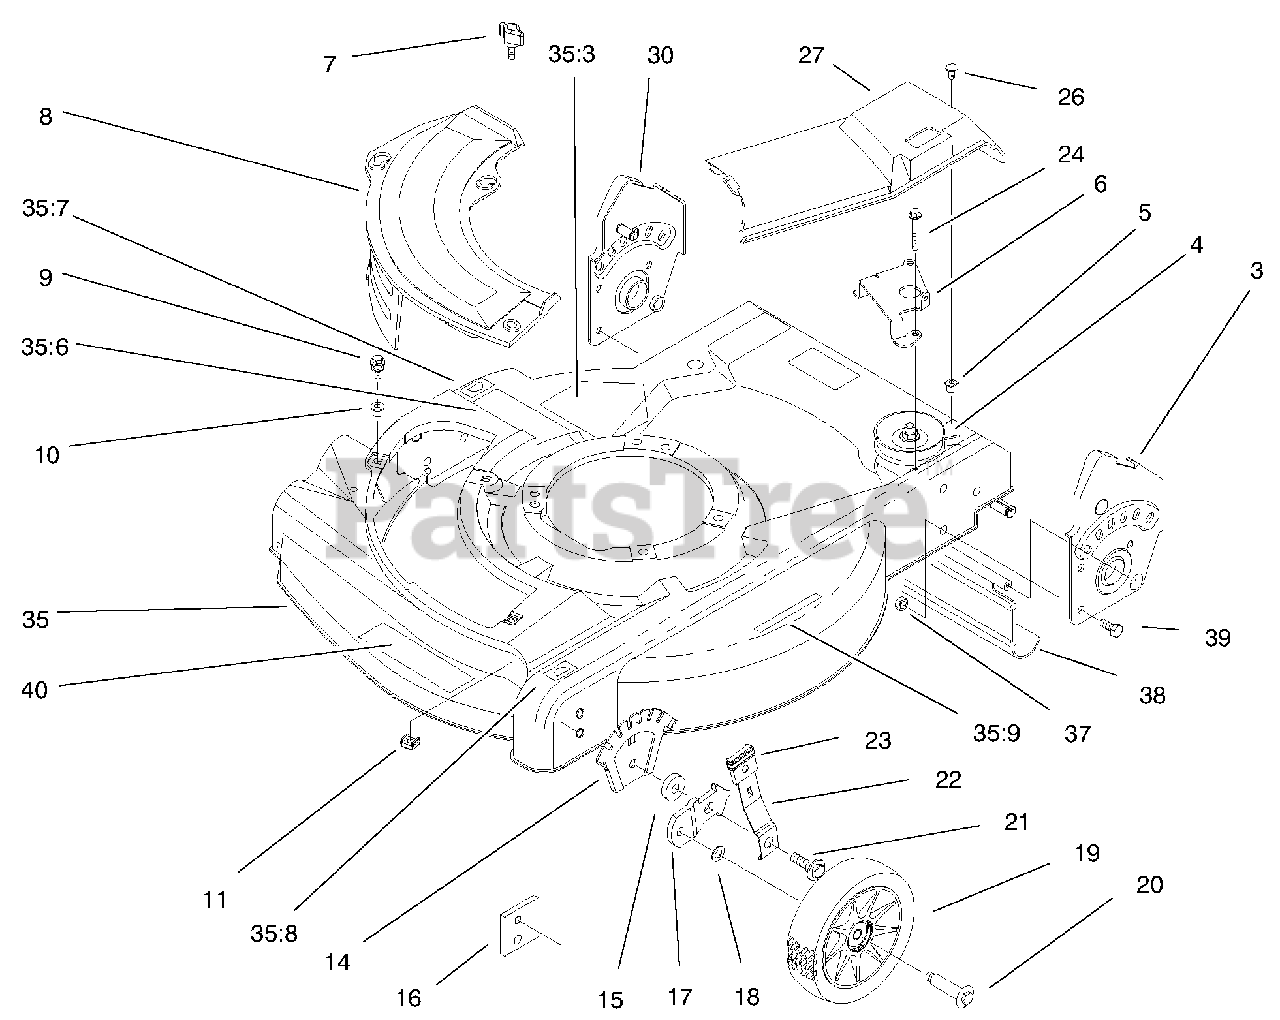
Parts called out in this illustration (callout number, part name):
3	LH Handle Brkt ASM
4	Gear Case Assembly
5	Grommet
6	Guide-Transmission
8	Plate-Mulch
9	Screw-Sems
10	Grommet-Plastic
11	Nut-Cage
14	Plate-Hght Adj
15	Washer-Wheel
16	Plate-Baffle
17	Bracket-Wheel Ht Adj
18	Washer-Wheel Bolt
19	6" Wheel & Tire ASM
20	Bolt-Shoulder 6" Wheel
21	Bolt-Shoulder
22	Arm-Front Spring
23	Knob-Height Adj Lever
24	Screw-Thread Forming
26	Screw-PTH
27	Cover-Drive
30	RH Handle Brkt ASM
35	ASM-Hsg/Baffle w/Decals
35:3	Decal-Danger
35:6	Decal-Warning
35:7	Decal-HOC R
35:8	Decal-HOC L
35:9	Decal-Safety Instruct
37	Nut-Lock NI
38	Shield-Trailing
39	Screw-HH
40	Decal-Deck
